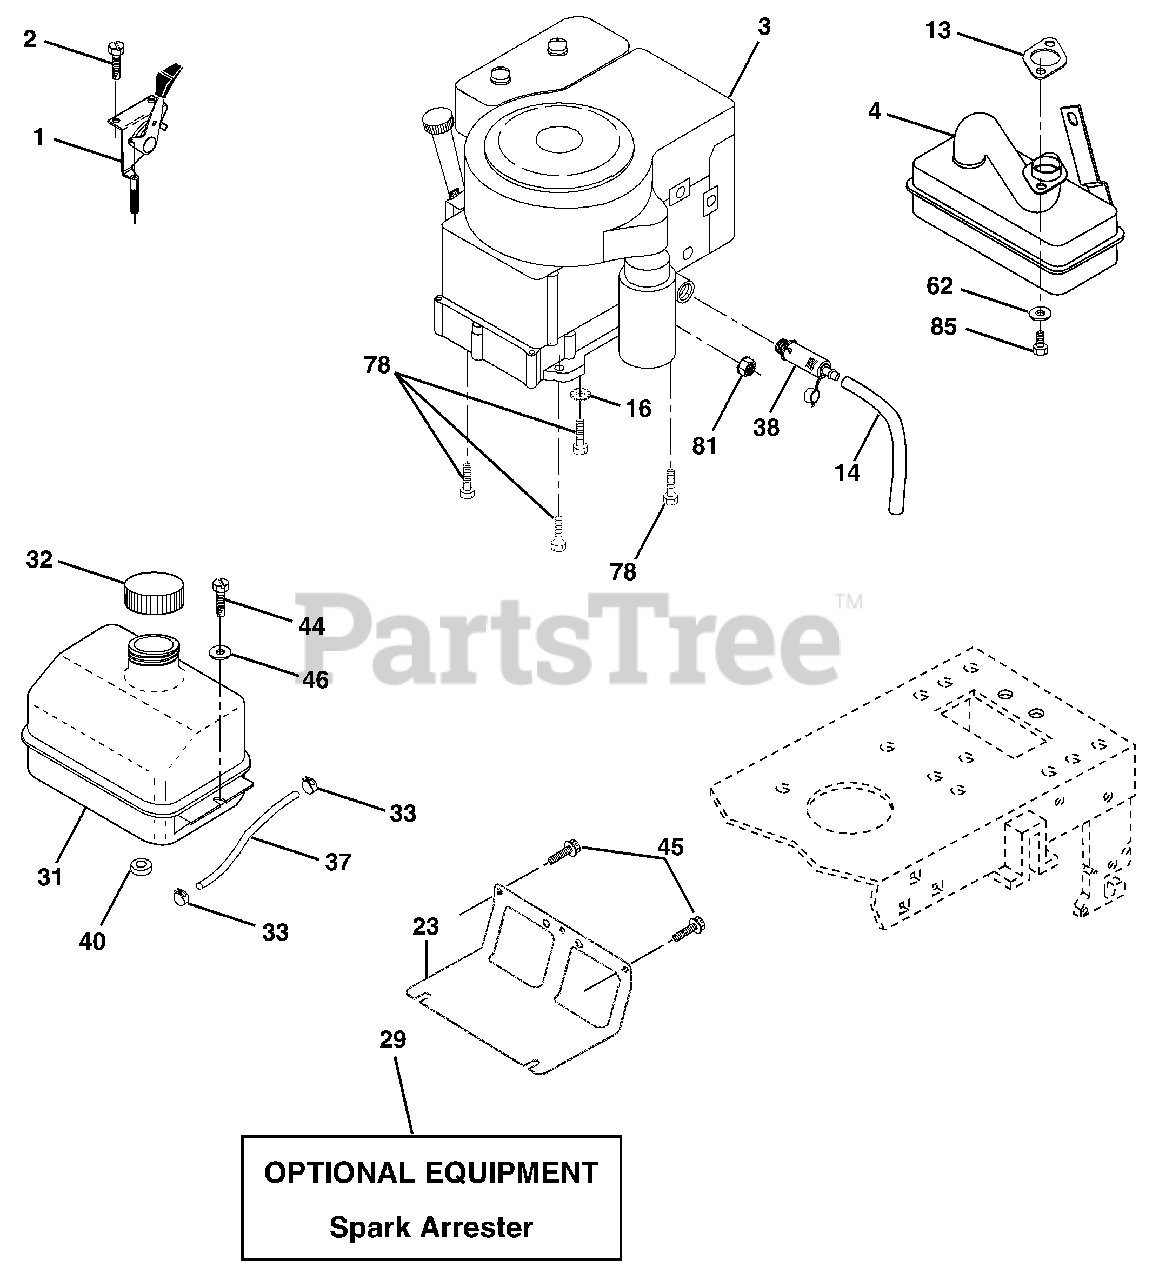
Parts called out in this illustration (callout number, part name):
1	Control Throt /Ch Flag
2	Screw Hex Thd Cut 1/4-20x1/2
4	Muffler Exhaust
13	Gasket
14	Tube Drain Oil Easy
16	Washer Lock Ext Tooth 3/8
23	Shield Browning/Debris Guard
29	Arrestor Spark
31	Tank Fuel 1 25 Fr
32	Cap Asm Fuel W/sym Vented
33	Clamp Hose Blk
37	Line Fuel 20"
38	Plug Drain Oil Easy
40	Bushing Snap Nyl Blk Fuel Line
44	Screw Hexwsh Thdrol 1/4-20x3/4
45	Screw Hex Wsh Thdrol 3/8-16
46	Washer 9/32 X 7/8 X 16ga
62	Washer Lock Hvy Hlcl Spr 5/16
78	Screw 3/8-16x1-1/4
81	Nut Keps Hex 1/4-20 Unc
85	Bolt Hex Hd Phillips
